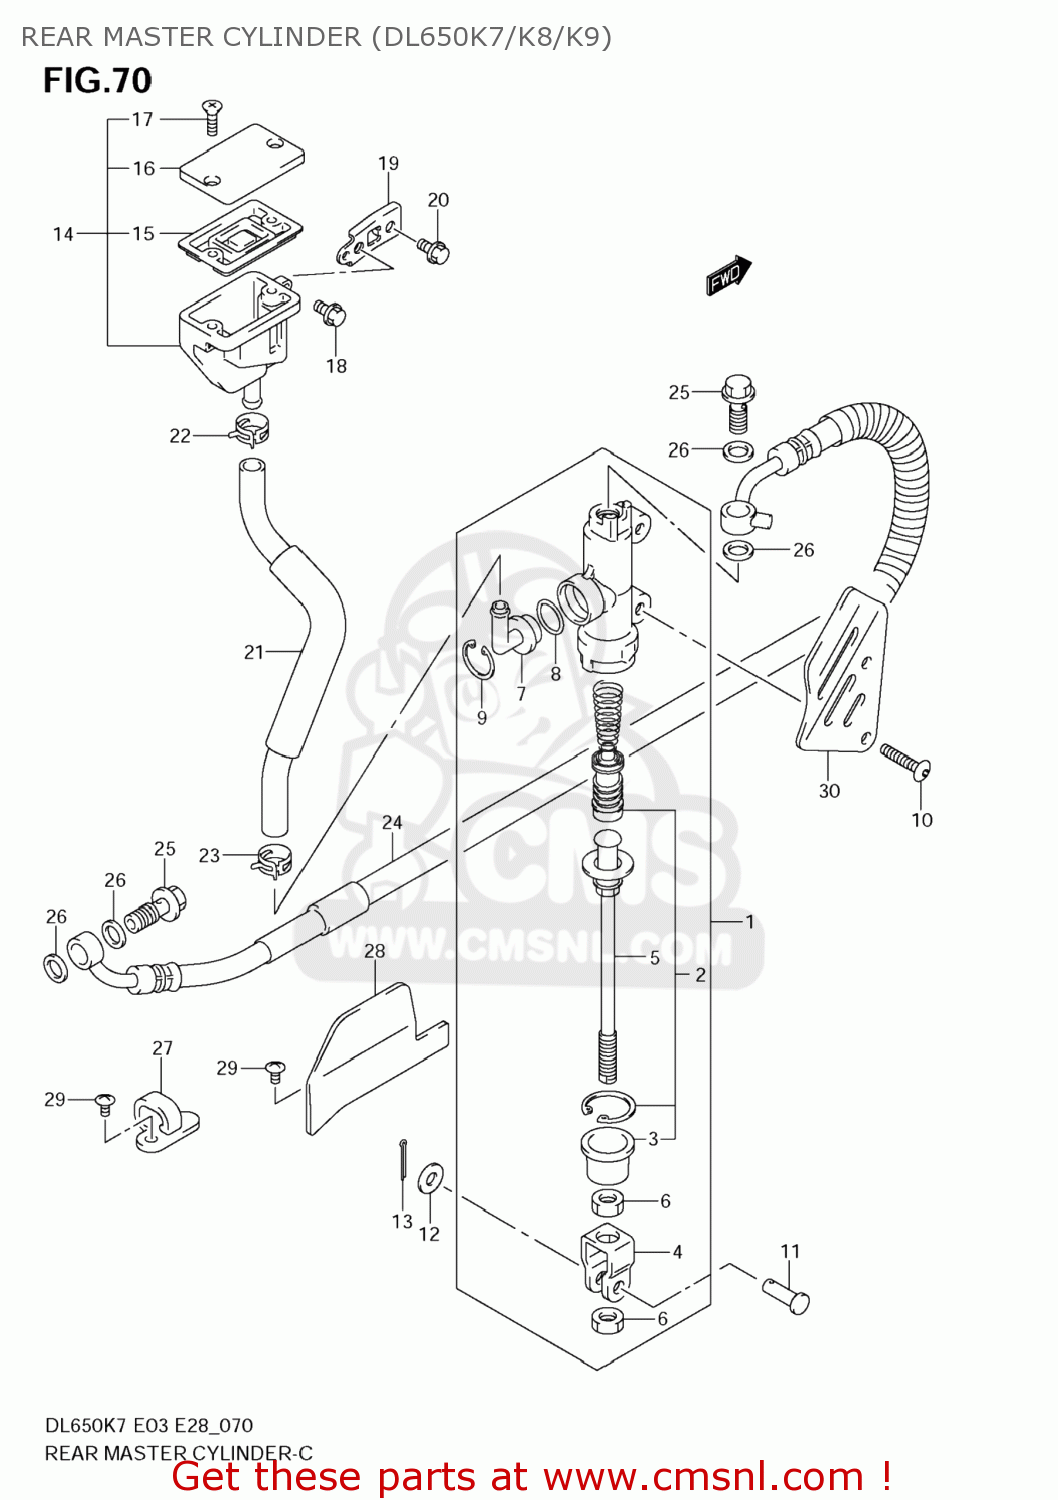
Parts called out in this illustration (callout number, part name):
1	CYLINDER ASSY,RR MASTER
2	PISTON/CUP SET
3	BOOT
4	YOKE
5	ROD,PUSH
6	NUT
7	CONNECTOR
8	O RING
9	CIRCLIP
10	SCREW(6X25)
11	PIN(6X18.2)
12	WASHER
13	PIN
14	TANK ASSY,RR RESERVOIR
15	DIAPHRAGM
16	CAP
17	SCREW
18	BOLT
19	BRACKET,RR RES
20	BOLT
21	HOSE,RR RESERVOIR TANK
22	CLIP
23	CLIP
24	HOSE,RR BRAKE
25	BOLT UNION
26	WASHER(10X15X1.5)
27	GUIDE,REAR BRA
28	GUIDE,RR BRAKE HOSE FR
29	SCREW
30	COVER,RR MASTER CYLINDER
